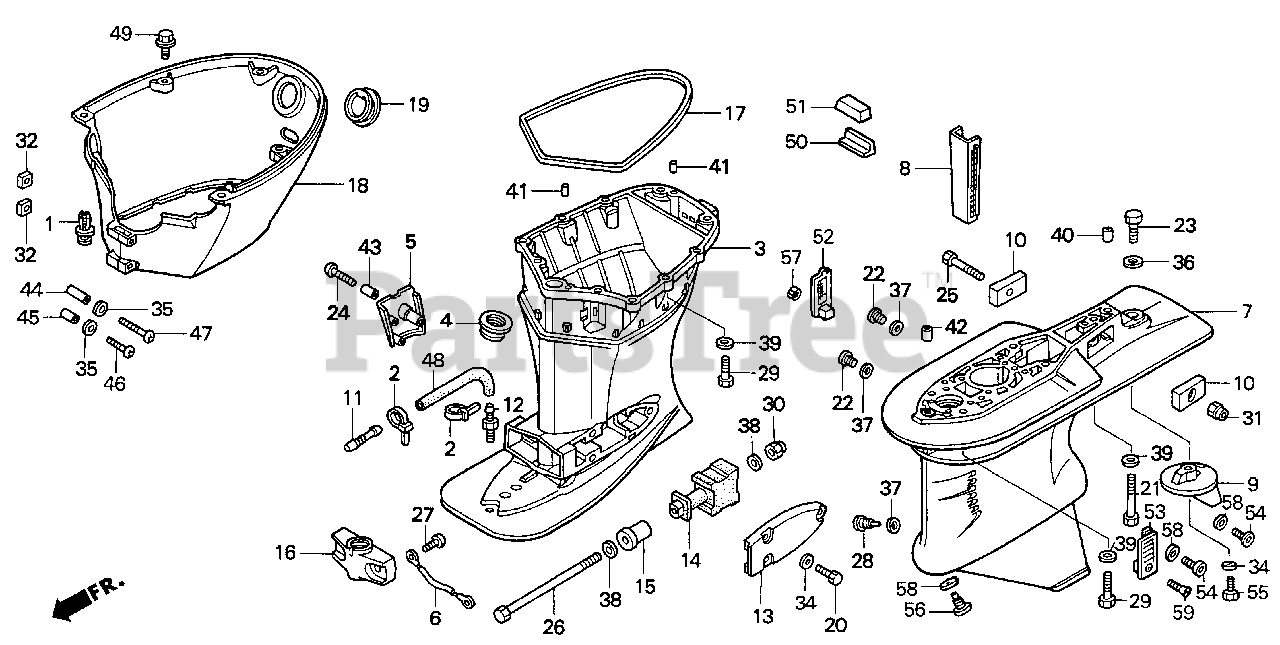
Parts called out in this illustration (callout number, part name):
1	CLIP, FUEL PIPE (BLACK)
2	BAND, WIRE
3	CASE, EXTENSION *NH282MU* (L) (OYSTER SILVER METALLIC-U)
4	RUBBER, DRAIN PLUG
5	COVER, DRAIN PLUG *NH282MU* (OYSTER SILVER METALLIC-U)
6	WIRE, LEAD
6	WIRE, LEAD (1.5X116MM)
7	CASE, GEAR *NH282MU* (OYSTER SILVER METALLIC-U)
9	TAB, TRIM *NH282MU* (OYSTER SILVER METALLIC-U)
10	METAL, ANODE
11	END, NIPPLE
12	NIPPLE, SENSOR
13	HOUSING, MOUNTING (LOWER) *NH282MU* (OYSTER SILVER METALLIC-U)
14	RUBBER, MOUNT (LOWER)
15	COLLAR, MOUNTING (LOWER)
16	HOUSING, CENTER MOUNTING (LOWER) *NH282MU* (OYSTER SILVER METALLIC-U)
17	RUBBER, COVER (LOWER)
18	COVER (LOWER) *NH282MU* (OYSTER SILVER METALLIC-U)
19	GROMMET, COVER (LOWER)
20	BOLT, HEX. (8X30)
24	SCREW, SPECIAL (6X35)
25	BOLT, HEX. (6X32)
26	BOLT, HEX. (12X225)
27	SCREW, PAN (6X8)
29	BOLT, HEX. (10X40)
30	NUT, SELF-LOCK (12MM)
31	NUT, SELF-LOCK (6MM)
32	NUT, PLATE (5MM)
34	WASHER, PLAIN (8MM)
35	WASHER, PLAIN (5MM)
38	WASHER, PLAIN (12MM)
39	WASHER, PLAIN (10MM)
41	PIN, DOWEL (6X10)
43	COLLAR, DISTANCE (6X10.5X25)
44	COLLAR, DISTANCE (5X7X38)
45	COLLAR, DISTANCE (5X7X23)
46	SCREW, PAN (5X30)
47	SCREW, PAN (5X45)
48	BULK HOSE, VACUUM (5X3000) (5X200)
49	BOLT, FLANGE (6X12)
50	PLATE, RUBBER SETTING
51	GROMMET, GEAR CASE
52	SCREEN, R. WATER
53	SCREEN, L. WATER
54	BOLT, OIL CHECK (8X8)
55	BOLT, HEX. (8X25)
56	BOLT, DRAIN PLUG (8MM)
57	NUT, SELF-LOCK (5MM)
58	WASHER, NYLON (8MM)
59	SCREW, OVAL (5X45)
